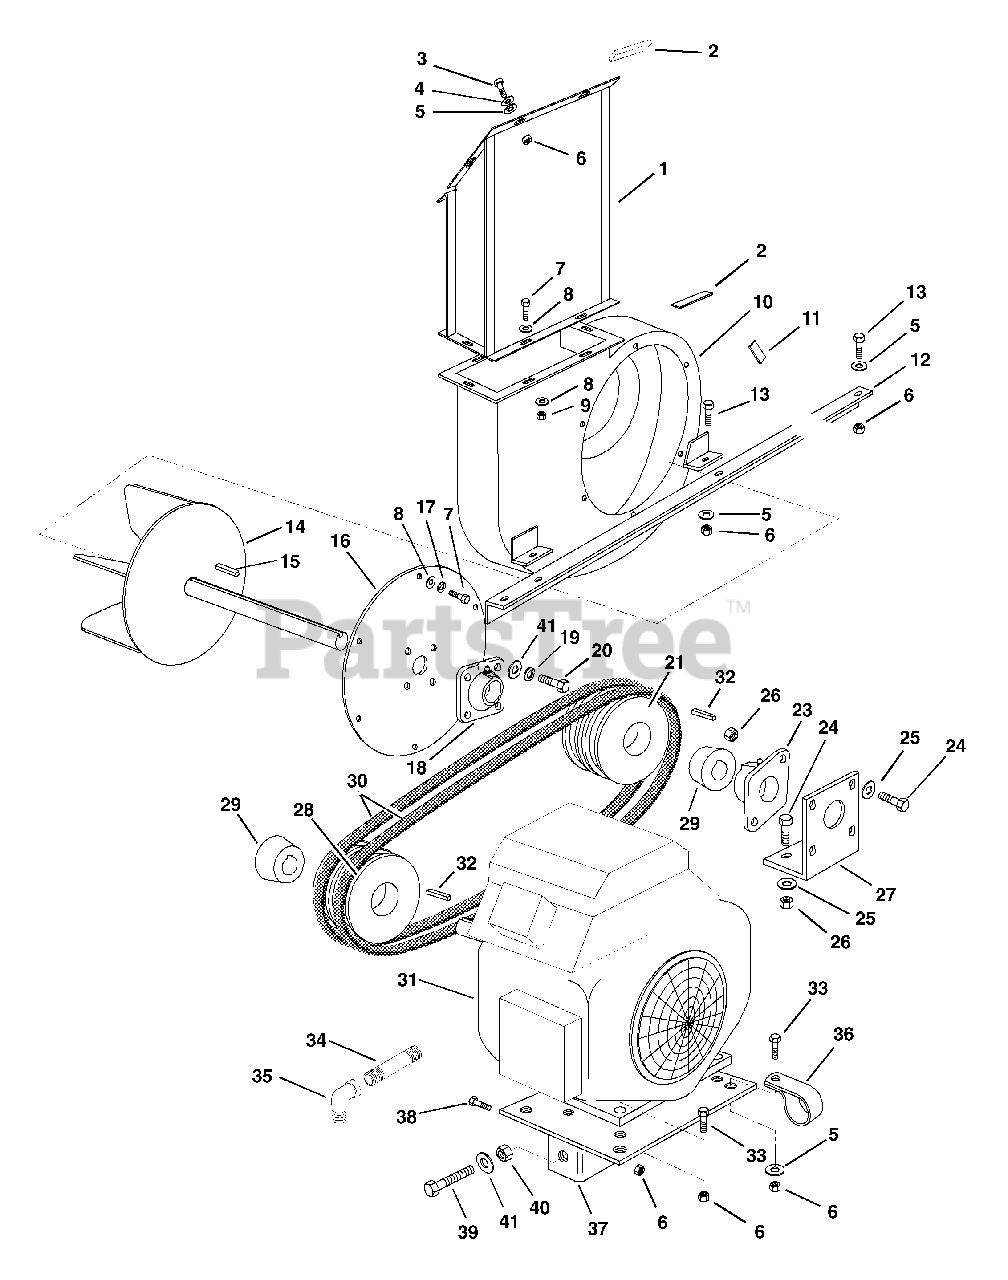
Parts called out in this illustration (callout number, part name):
1	Discharge Chute Weldment
3	Bolt-Hex .38-16 x .75 Grade 5
4	Washer-Flat-Steel .511 x 1.441 x .125
5	Washer-Flat-Steel .438 x 1.00 x .083
6	Nut-Locking-Center .38-16
7	Bolt-Hex .31-18 x .75 Grade 5
8	Washer-Flat-Steel .38 x .875 x .083
9	Nut-Locking-Center .31-18
10	Blower Weldment
11	Gasket
12	Blower Support Beam
13	Bolt-Hex .38-16 x 1.00 Grade 5
14	Fan
15	Key-Square .38 x .38 x 2.00
16	Fan Cover Weldment
17	Washer-Lock .31 x .078
19	Washer-Lock .44 x .109
20	Bolt-Hex .44-14 x 1.25 Grade 5
21	Pulley - V 2G 3V 6.5 Taper Lock
22	Bushing, Driven Sheave
23	Bearing, 2-Bolt
24	Bolt-Hex .50-13 x 1.50 Grade 5
25	Washer-Flat Steel .563 x 1.38 x .109
26	Nut-Locking-Center .50-13
27	Bearing Holder
28	Pulley - V 2G 3V 5.5 Taper Lock
29	Bushing, Drive Sheave
30	V-Belt (Matched Set of 2)
31	Engine-18 HP Kohler Command
31	Engine-18 HP Robin Pro Vac
32	Key-Square .25 x .25 x 1.25 SAE
33	Bolt-Hex .38-16 x 3.00 Grade 5
34	Nipple
35	Elbow .375-18 NPTF
37	Engine Base Weldment
38	Bolt-Hex .38-16 x 1.25 Grade 5
39	Bolt-Hex .50-13 x 5.00 Grade 5
40	Nut-Hex .50-13
41	Washer-Flat-Steel .50 x 1.25 x .083
